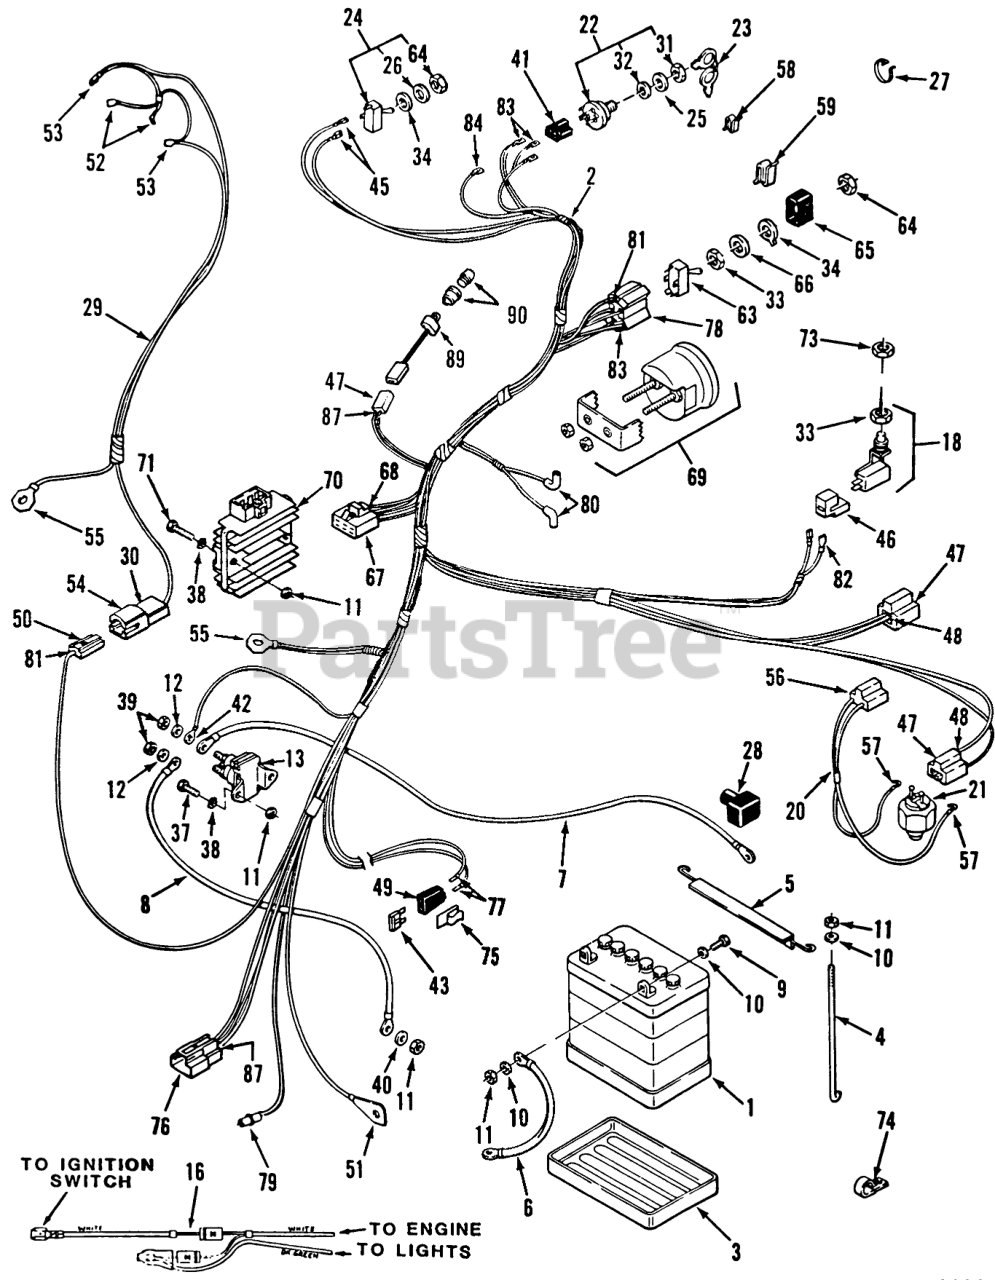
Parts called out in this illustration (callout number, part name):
1	Battery
2	WIRING-HARNESS & DIA
2	MAIN-HARNESS & DIA
3	TRAY BATTERY
5	HOLDDOWN-BATTERY
6	WIRE -BLACK
7	WIRE - 14" BLACK
8	ASSY WIRE
9	Bolt
11	Nut
12	Washer
13	Solenoid (Includes two of item 11) 208, 211
16	DIODE-KIT SERVICE
18	Seat Switch
20	ASSY WIRING HARNESS
21	SWITCH (N.C.-TRANS)
22	Ignition Switch (includes items 31 & 32)
23	Ignition Key
24	Light Switch 211, 212 (includes items 33 & 34)
25	Washer
26	Washer
27	PLASTIC TIE
28	Boot
29	HARNESS
29	Headlight Harness 212
30	Connector (part of item 29)
32	LOCKWASHER
33	NUT-HEX, SPECIAL
34	TAB-WASHER
37	Screw
38	LOCKWASHER
39	Nut
40	Washer
41	CONNECTOR-5 WAY-SERV
42	Ring Terminal (part of item 2)
43	FUSE-BLADE, 15 AMP
43	FUSE-BLADE, 25 AMP
45	Connector .250 x .032
46	CONNECTOR BODY
47	CONNECTOR BODY
48	TERMINAL-LONG MALE
49	AUTO-FUSEBLOCK TERM
49	FUSE-BLOCK ASS'Y
50	CONNECTOR BODY ELECT
51	Ring Terminal
52	Male Terminals (Part of 1)
53	Female Dbl. Crimp Terminal (part of item 29) 211
54	Connector Part of 5
55	Ring Terminal (part of item 2)
56	CONNECTOR BODY B
57	TERMINAL-TAB RCPT
58	CLIP
59	SPEED CLIP
63	Electric Clutch Switch (includes items 33, 34 & 64) 208, 211
63	Electric Clutch Switch (includes items 33, 34 & 64) 212
65	COVER-PTO SWITCH
66	WASHER
67	CONNECTOR BODY
68	Terminal 212 (part of item 2)
69	Voltmeter (Includes 109650 Clamp & 5924 #10-32 Nut)
70	SPRING-BRUSH
71	HHCS 1/4-20X1" WHIZ
73	NUT-HEX, SPECIAL
74	CLAMP
76	3-CONTACT LOCK-TYPE
77	Fuse Holder Term. (1 used on 212) 208, 211
77	Fuse Holder Terminal 212
78	CONNECTOR 5 WAY
79	Connector-Socket
80	Right Angle Terminal #10 211, 212
81	Wire Terminal (Part of 1)
82	Wire Terminal (Part of 1)
83	Male Terminals (Part of 1)
84	Connector .250 x .032
87	Long Male Terminal .248 x .032
89	LIGHT-OIL INDICATOR
90	ASSY LENS & BUSHING
